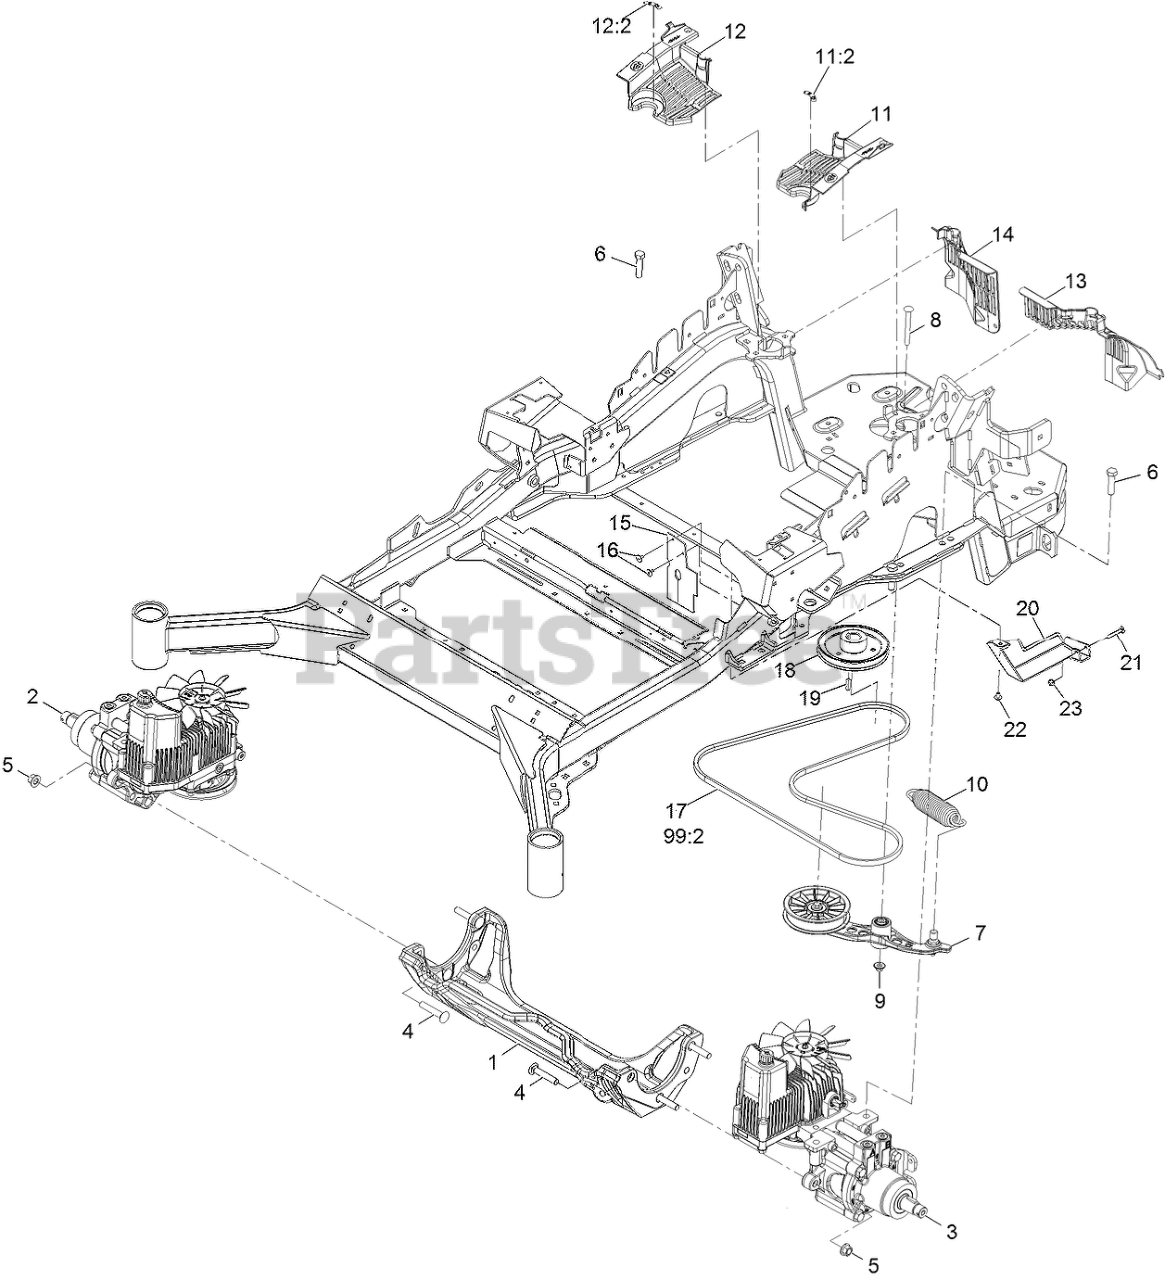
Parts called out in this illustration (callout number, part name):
1	CRADLE-HYDRO
2	Hydro-RH
3	Hydro-LH
4	SCREW-CARR
5	Nut-Lock 1/2-13
6	SCREW-HH
7	PUMP IDLER ASM
8	BOLT-SHOULDER, CARRIAGE 3/8-16 X 3 1/2
9	Nut-Nyloc 3/8-16 Flg
10	SPRING-EXTENSION
11	LH HYDRO GUARD ASM
11:2	DECAL-OIL, HYDRO
12	RH HYDRO GUARD ASM
12:2	DECAL-OIL, HYDRO
13	GUARD-HYDRO REAR, LH TRIM
14	GUARD-HYDRO, REAR (RH)
15	DEFLECTOR-AIR FLOW
16	RIVET-POP
18	SHEAVE
20	TANK GUARD WLDMNT
21	SCREW-CARR
22	SCREW AND WASHER ASM
